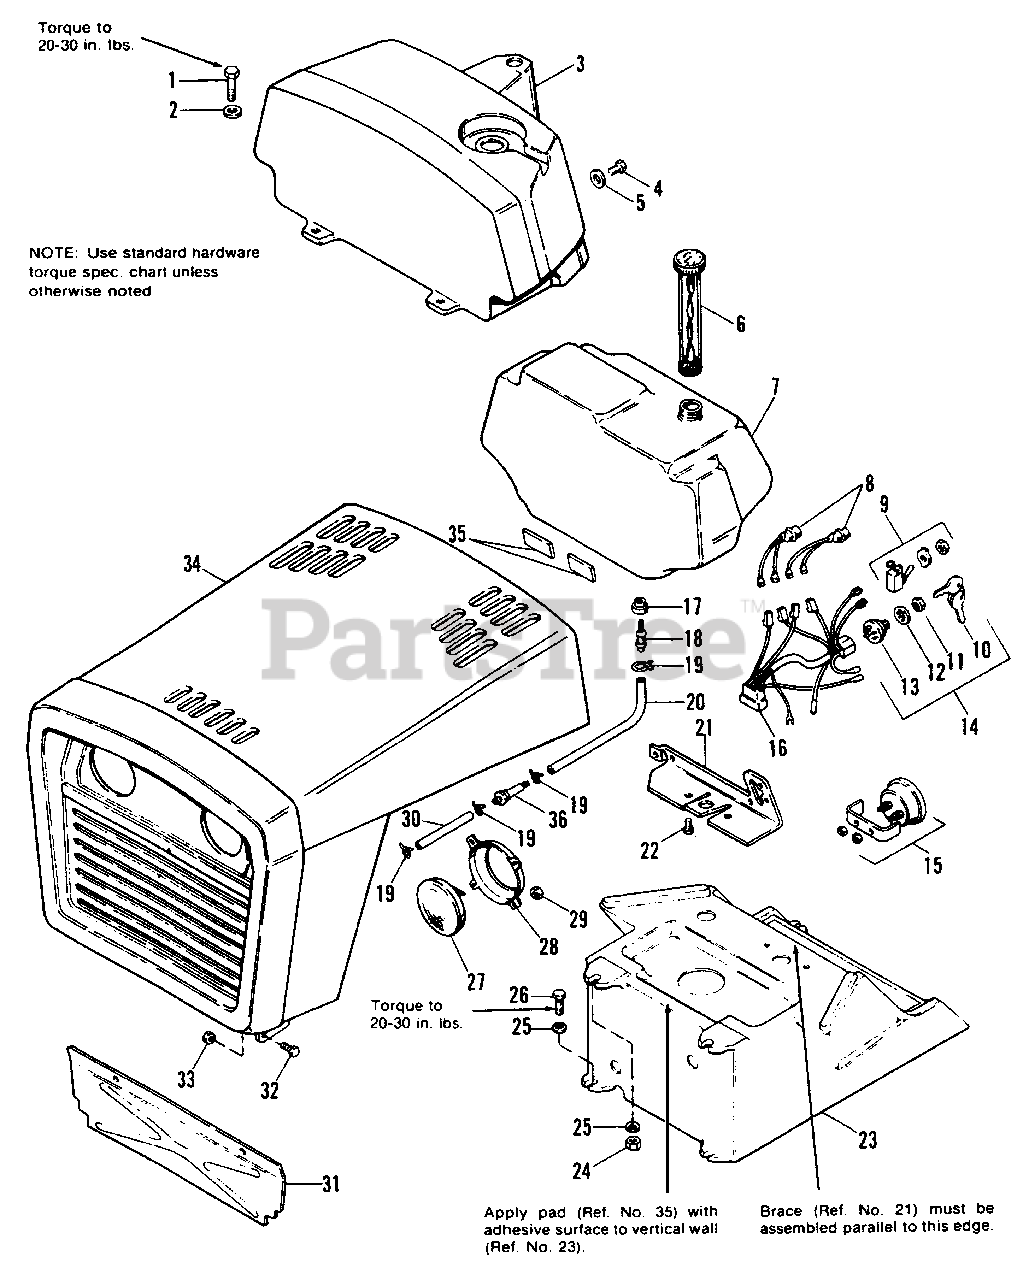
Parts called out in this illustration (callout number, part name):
1	CAPSCREW, Hex, 1/4-20 x 1-1/4
2	WASHER, Plain, 1/4
3	DASH BOARD, Top
4	SCREW, #14 x 3/4
5	WASHER, Plain, 3/16
7	TANK ASSY., Fuel
8	LIGHT, Indicator
9	SWITCH, Toggle
11	NUT, Hex, 5/8-32
12	LOCKWASHER, Int., 5/8
13	SWITCH
14	SWITCH ASSY., Ignition
15	AMMETER
16	HARNESS, Upper
18	FITTING, Elbow
19	CLAMP (Qty. 3 used on 6116 & 6118)
20	HOSE, Fuel (12" long)
21	BRACE, Dash
22	SCREW, Taptite, 1/4-20 x 3/4
23	DASHBOARD, Bottom
24	LOCKNUT, Hex, 1/4-20
25	LOCKWASHERS, Dished, 1/4
26	SCREW, Taptite, 1/4-20 x 1
28	BRACKET, Headlight Support
29	LOCKNUT, Pal, #10-24
30	HOSE, Fuel (4-3/8" long)(Used on 6108 & 6111)
31	BAFFLE, Engine, Front (Used on 6116 & 6118)
32	CAPSCREW, Hex, 3/8-16 x 7/8
33	LOCKNUT, Hex, 3/8-16
34	HOOD & GRILLE ASSY.
36	FILTER, Fuel
